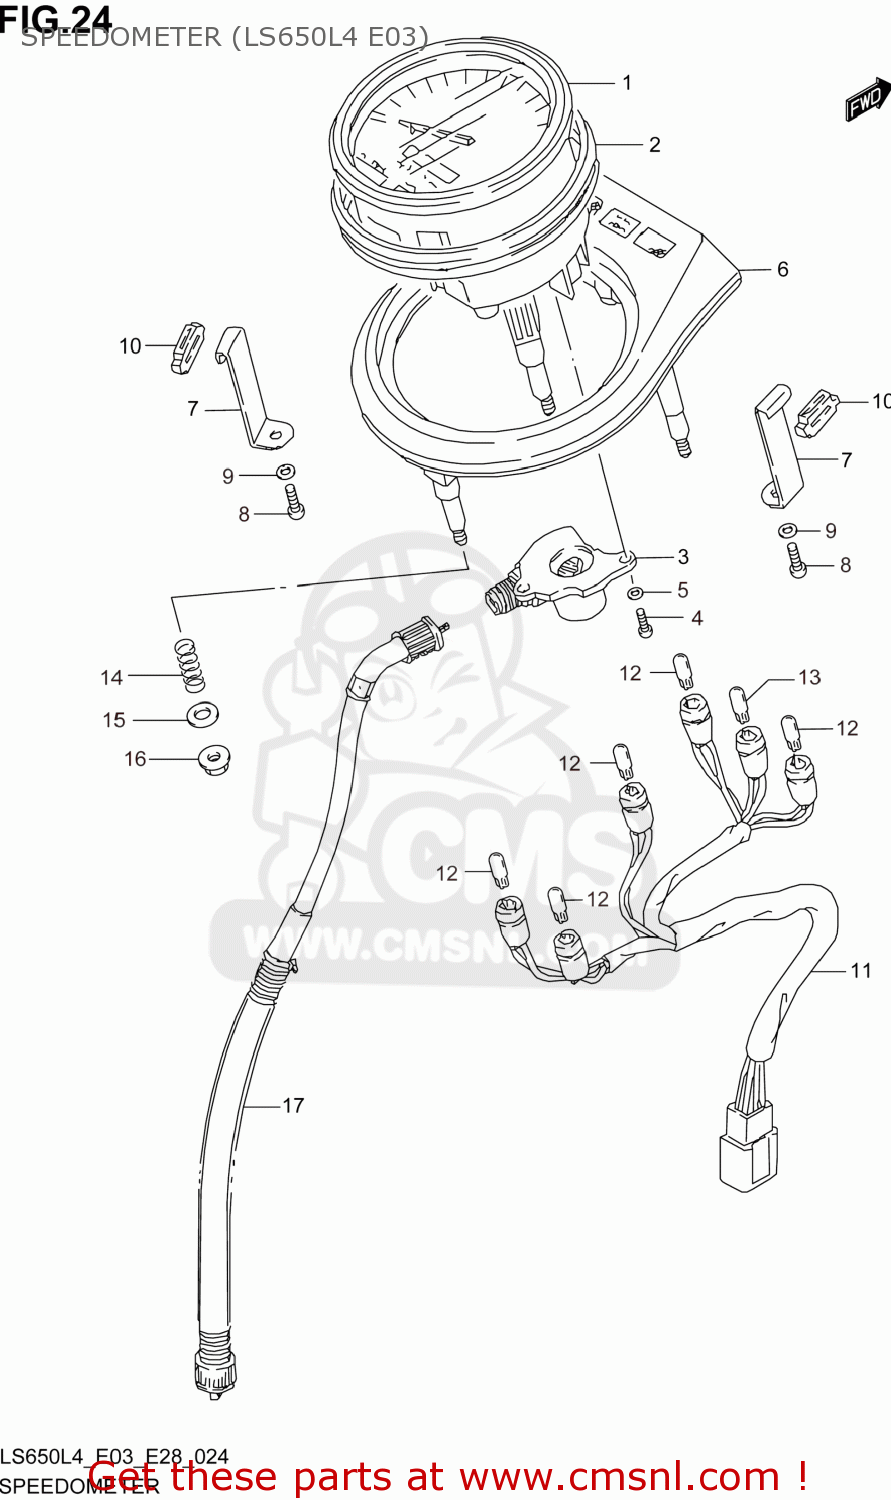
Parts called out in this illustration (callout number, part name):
1	SPEEDOMETER(MILE/KILO)
2	CUSHION,METER
3	BOX,GEAR
4	SCREW
5	WASHER,LOCK
6	HOOD,METER
7	BRACKET,METER
8	SCREW
9	WASHER,LOCK
10	CUSHION
11	SOCKET,METER
12	BULB(12V3W,T6.5)
13	BULB(12V1.7W,T6.5)
14	SPRING
15	WASHER(5.5X14X1.2)
16	NUT
17	CABLE ASSY,SPEEDOMETER
